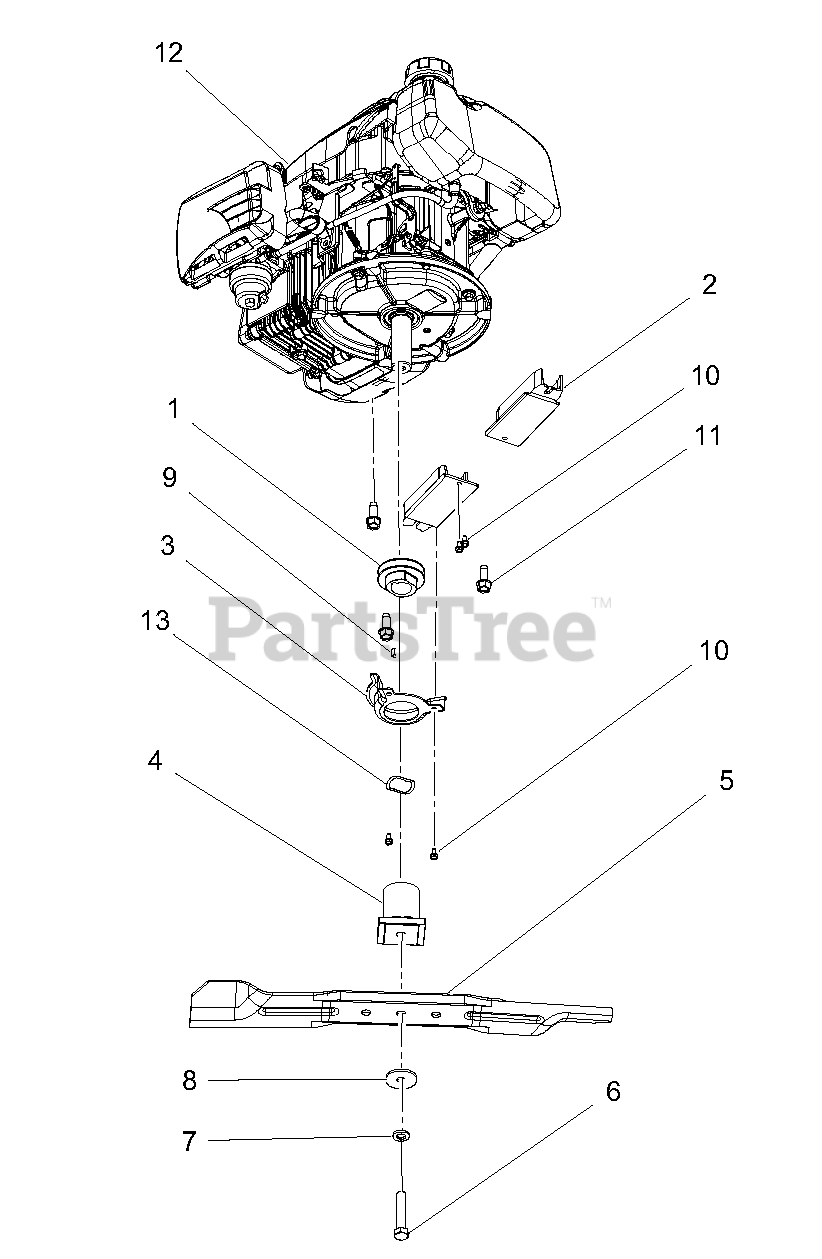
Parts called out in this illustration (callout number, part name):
1	PULLEY, GROUND DRIVE, LM (911174, 178)
2	GUIDE, BELT - INNER
3	GUIDE, BELT CRANKSHAFT (911174, 178)
4	ADAPTOR, BLADE
5	BLADE, MOWER 21" HIGH-LIFT
6	@BLT-HEX .44-20X2.25 GR8 YWZC
7	@WSHR-LK .44X.109 REG YWZC
8	WSHR-FL-STL .4375X1.50X.125 YWZC
9	KEY-SQ .188X.188X.625 (911174, 178)
10	SCR, TAP 10-24X.375 PRE-COAT 80 (911174, 178)
10	SCR, TAP 10-24X.375 PRE-COAT 80 (911172)
11	SCR-TAP .38-16X1.00 HWH TR YZ
12	ENGINE, SUBARU (911174)
12	ENGINE, SUBARU, ELECTRIC (911178) N/S
12	ENGINE, SERVICE, AC SERIES (911172) N/S
13	WASHER, WAVE (911174, 178)
